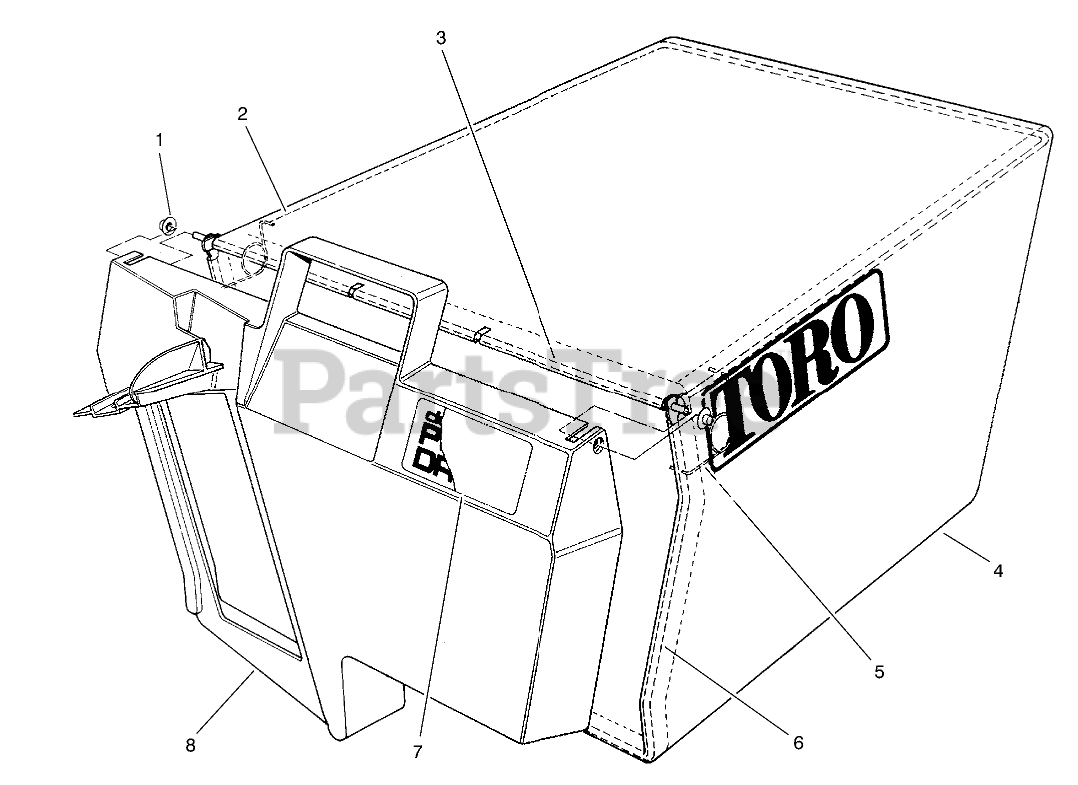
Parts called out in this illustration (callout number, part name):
1	NUT-PUSH
2	FRAME-BAG, UPPER
3	HINGE-DOOR, BAG
4	Bag
5	SPRING
6	FRAME-BAG
7	BAG DOOR DECAL
8	DOOR-BAG
